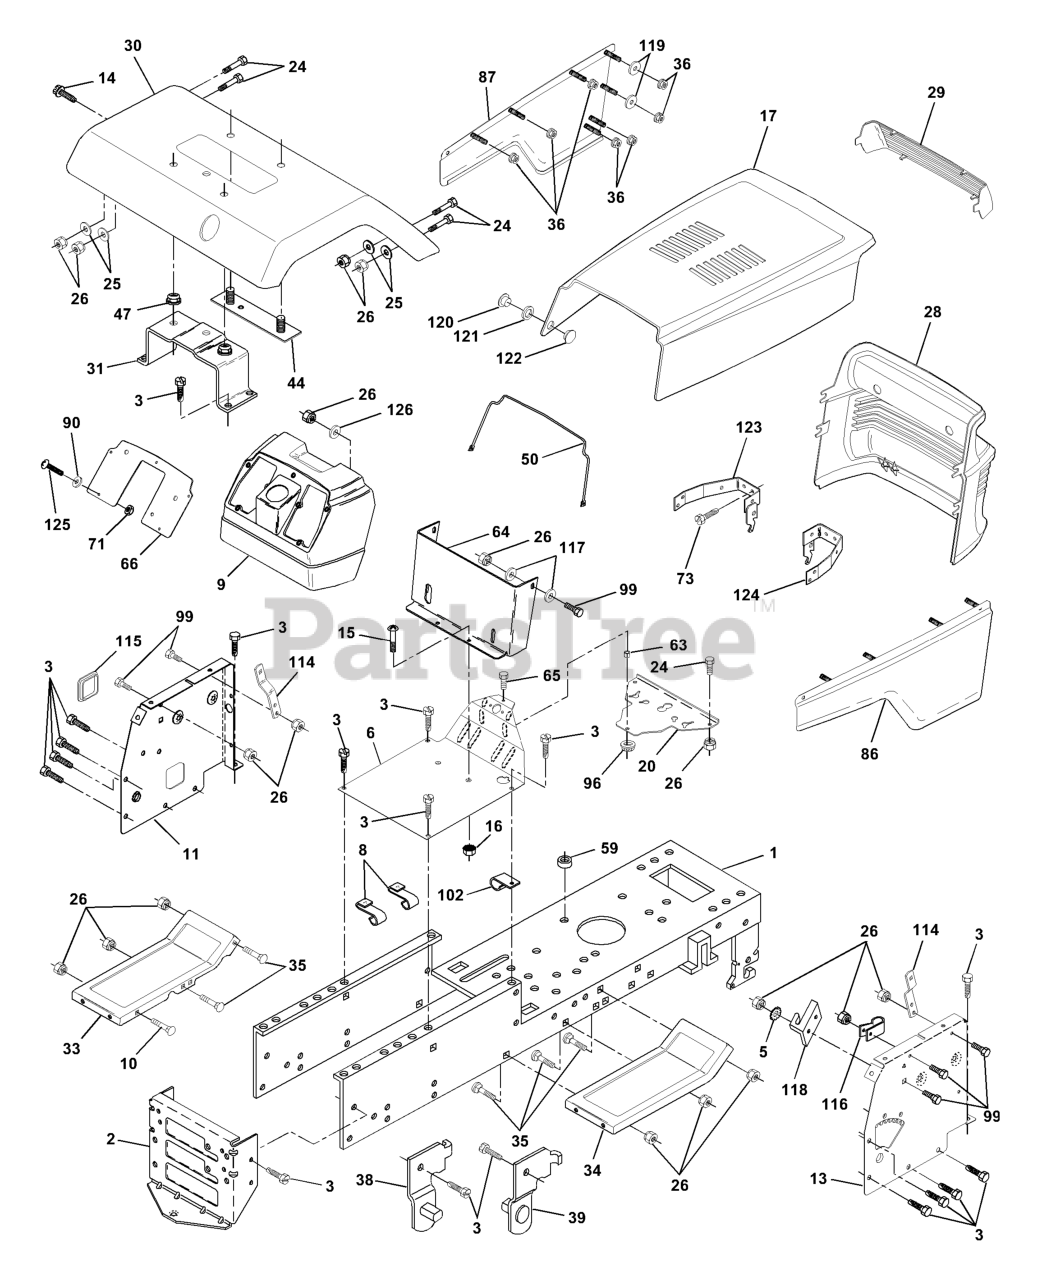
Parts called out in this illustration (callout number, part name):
1	CHASSIS
2	STRETCH DRAWBAR
3	SCREW
8	CLIP,INSULATOR
10	BOLT D
11	PANEL DASH LH
13	PANEL DASH RH
14	SCREW LT
15	Screw Mach Trhd 5/16 - 18 UNC x 3/4
16	NUT
17	HOOD.HUSQVARNA.ORANGE
20	PLATE, BATTERY
24	BOLT
25	WASHER
26	NUT
28	GRILL
29	LENS RH
30	FENDER
31	FENDER BRKT
33	ROLL PIN NLA
34	PAD,SPACER
35	BOLT
38	BRACKET LH PIVOT
39	BRACKET RH PIVOT
42	LENS LH
44	STRAP
47	NUT-PUSH YT
50	SUPPORT ASS'Y
51	LOCKNUT.NYLOC.1/4-20
59	SNAP BUSHING T
64	DASH LOWER YT NLA
65	Bolt Fin Hex 5/16 - 18 Unc x 2 Gr. 2
66	DASH PLATE
67	WASHER
68	NUT
69	STRAP ASSY LT
70	STRAP ASSY LT
71	Nut Keps Blk Hex 1/4-20 UNC
72	SUPPORT ASS'Y
75	BOLT T
76	BOLT
77	SCREW
78	LOCKWASHER #10
79	WELDNUT
80	LATCH.HOOD.
81	WING NUT
82	RP SCREW
85	NUT **
86	SIDE PANEL ASSY RH
87	SIDE PANEL ASSY LH
90	WASHER PM
91	NUT
92	LOCKWASHER
93	GRILL COMPLETE
95	SNAP CAP LT
96	NUT.71038.31-18.HEX.NYLOCK
97	SUPPORT RH YTH
98	SUPPORT LH YTH
99	BOLT
109	BRACKET BUMPER
110	PLUG PLASTIC
111	BOLT.3/8-14X1.25
112	WASHER
113	BUMPER ASSY
